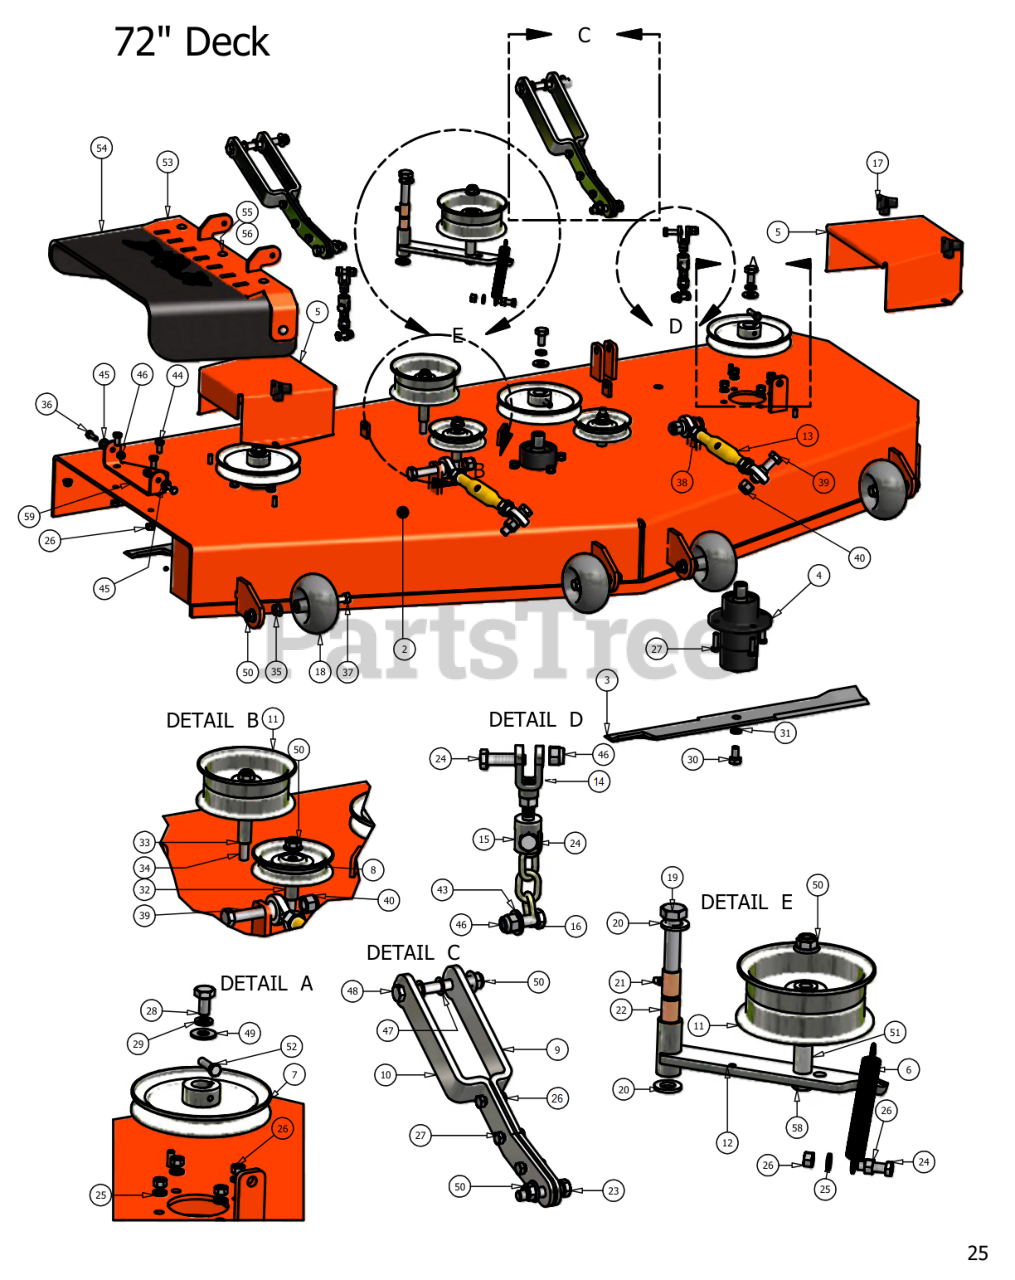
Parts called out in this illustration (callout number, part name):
1	72" Deck Belt
3	72" Fusion Blade
5	Pulley Guard
6	Deck Idler Spring
7	7" Deck Pulley
8	4 3/4" Idler Pulley
9	Deck Support Arm (Rigth)
10	Deck Support Arm (Left)
11	5 3/4" Flat Idler Pulley
12	Deck Idler Arm
13	Turnbuckle
14	Female Yoke
17	5/16" Knob
18	Anti-Scalp Rollers
19	5/8" x 4" Hex Bolt
20	.635 ID Plastic Washer
21	Grease Fitting (Drive-In Type)
22	5/8" ID x 1 1/8" Brass Bushing
23	1/2" x 2 1/2" Hex Bolt
24	3/8" x 1 1/4" Hex Bolt
25	3/8" Lock Washer
26	3/8" Hex Nut
27	3/8" x 1 1/4" Hex Bolt
28	1/2" x 1 1/2" Fine Thread Bolt
29	1/2" Lock Washer
30	5/8" x 1.5" Fine Threaded Bolt
31	5/8" Lock Washer
32	1 1/2" Pulley Spacer
33	1 3/4" Pulley Spacer
34	1/2" x 3 1/2" Bolt
35	1/2" Flange Nut
36	5/16" x 1" Hex Bolt
37	1/2" x 4" Bolt (Grade 8)
38	3/4" Left Handed Nut
39	5/8" x 2 1/2" Hex Bolt
40	5/8 Std NC Nylock Nut
41	3/8" Fine Threaded Jam Nut
43	3/8" Flat Washer
44	3/8" x 3/4" Hex Bolt
45	.360 ID Plastic Washer
46	5/16" Nylock Nut
47	1/2" Brass Washer
48	1/2" x 4 1/2" Bolt
49	1/2" Cupped Washer
50	1/2" Flange Lock Nut
51	1 1/4" Pulley Spacer
52	3/8" Hex Bolt
53	2007 Hanger Plate
54	Rubber Side Discharge
55	5/16" x 1 1/2" Carriage Bolt
56	5/16" Nylock Flange Nut
57	2007 Lower Hanger Plate
58	1/2" x 3" Bolt
59	2007 Lower Hanger Plate
